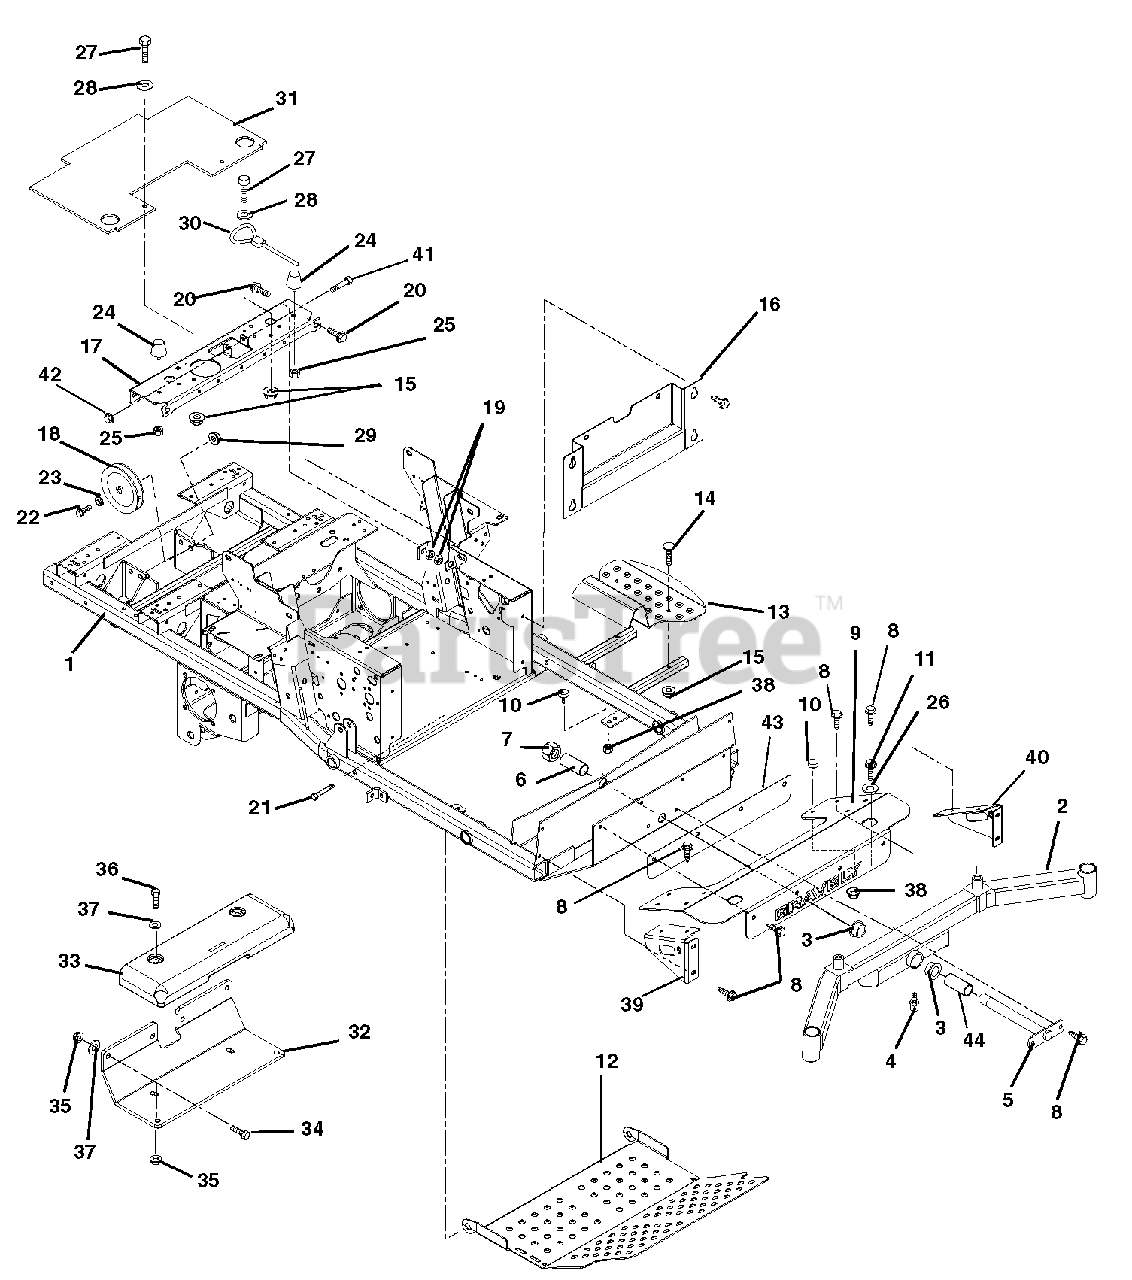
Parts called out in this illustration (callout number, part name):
1	Weldment, Frame
2	Weldment, Front Axle
3	Bushing, Flange 1.25 x 1.50 x 1.00 x .200
4	Fitting, Lube 45 Degree GM411031
5	Pin, Axle
7	Nut, Locking Nylon 1.0-14
8	Screw, Tapping .38-16 x .75
9	Axle Cover
10	Button, Bumper
11	Bolt, Hex .50-20 x 1.00 Grade 5
12	Panel, Inspection
13	Step, Ingress
14	Bolt, Round Head Square Neck .31-18 x 1.75 Grade 5
15	Nut, Locking Top Flange .31-18
16	Plate, Kick
17	Channel, Cross
18	Pulley, Idler
19	Nut, Retainer .375-16 x .37
20	Bolt, Serrated Flange Washer Head .38-16 x 1.00
21	Bolt, Hex .50-13 x 3.25 Grade 5
22	Bolt, Hex .50-13 x 2.25 Grade 5
23	Washer, Flat Steel .505 x .88 x .072
25	Nut, Spin Lock Flange .312-18
26	Washer, Flat Steel .064 x 1.810 x .250
27	Bolt, Hex .31-18 x 1.00 Grade 5
28	Washer, Flat Steel .344 x 1.125 x .135
29	Nut, Locking Top Flange .50-13
30	Cable, Seat Prop
31	Guard, Grass
32	Bracket, Weight
33	Weight, Cast Iron
34	Bolt, Hex .50-13 x 1.25 Grade 5
35	Nut, Locking Top Flange .50-13
36	Bolt, Hex .50-13 x 4.50 Grade 5
37	Washer, Flat Steel .531 x 1.06 x .095
38	Nut, Spin Lock, Flange .312-18
39	Weldment, Right Hand Axle Cover Support
40	Weldment, Left Hand Axle Cover Support
41	Bolt, Hex .38-16X3.00 Grade 5
42	Nut, Locking-Top-Flange .38-16
43	Plate, Backer
44	Spacer, 1.25 OD x 1.0 ID x 3.63
